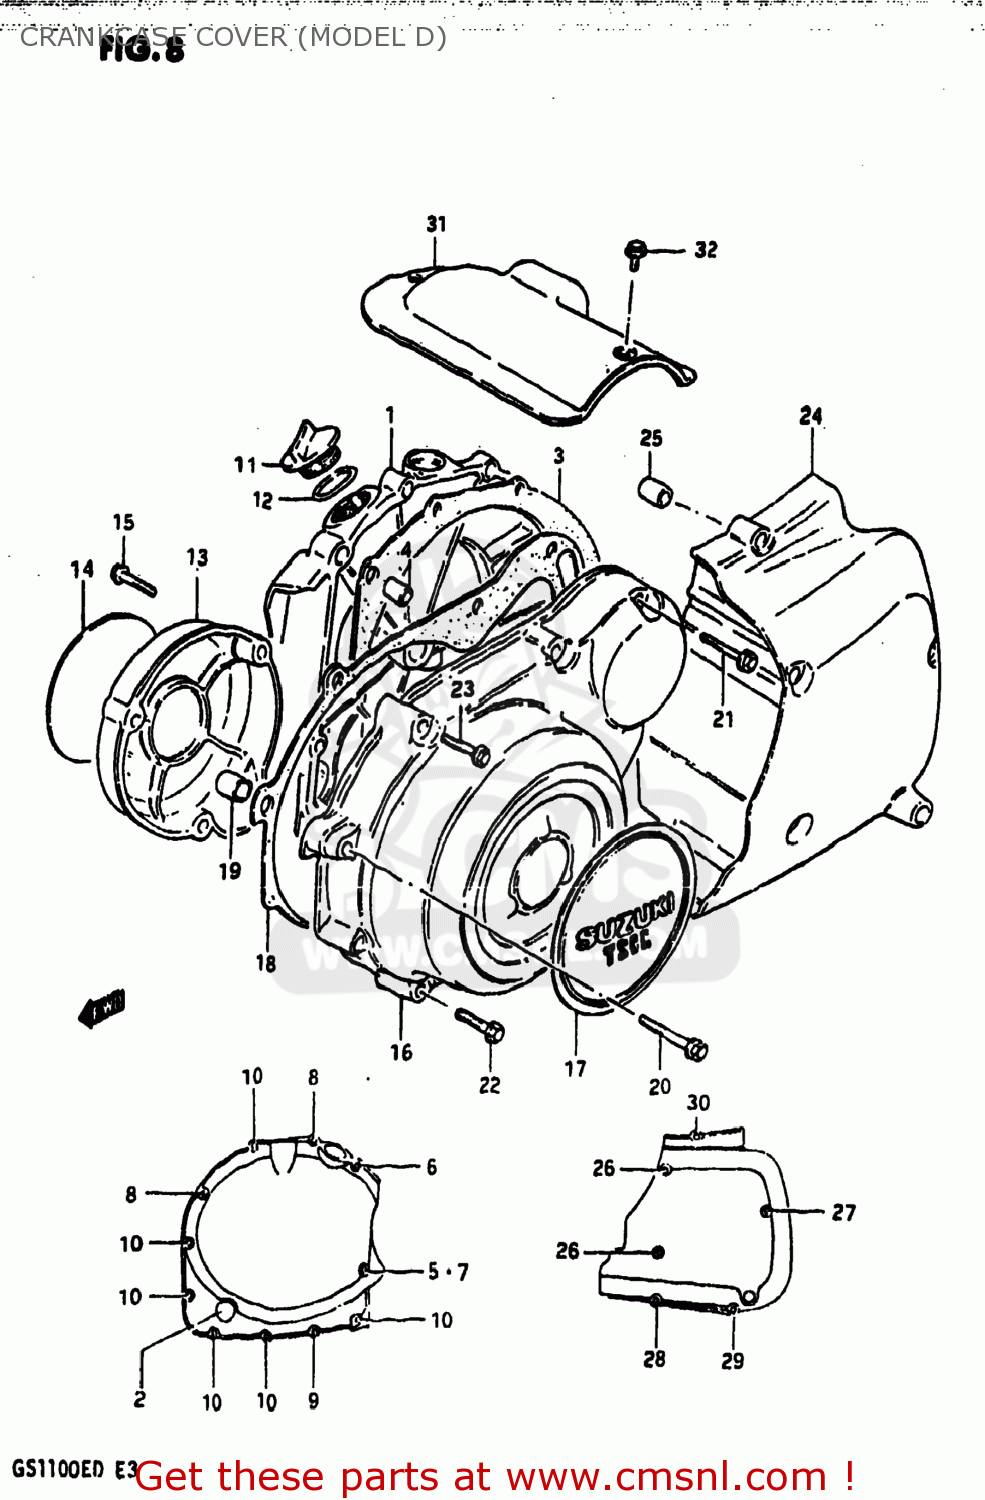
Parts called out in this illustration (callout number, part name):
1	COVER,CLUTCH
2	LENS,OIL LEVEL CHECK
3	GASKET,CLUTCH COVER (MCA)
4	PIN
5	GASKET (NAS)
6	BOLT (6X40)
7	BOLT (6X35)
8	BOLT (6*30)
9	BOLT (6X25)
10	BOLT 6X20
11	CAP
12	O RING(D:2.2,ID:32)
13	COVER,CONTACT BREAKER
14	EMBLEM
15	BOLT (5X30)
16	COVER,MAGNETO
17	EMBLEM,MAGNETO COVER
18	GASKET,MAGNETO COVER (MCA)
19	PIN
20	BOLT (6X45)
21	BOLT (6X40)
22	BOLT (6X35)
23	BOLT (6*30)
24	COVER,ENGINE SPROCKET
25	PIN
26	BOLT (6X95)
27	BOLT (6X85)
28	BOLT (6X70)
29	BOLT (6X55)
30	BOLT (6*30)
31	COVER,STARTER MOTOR
32	BOLT (5X8)
